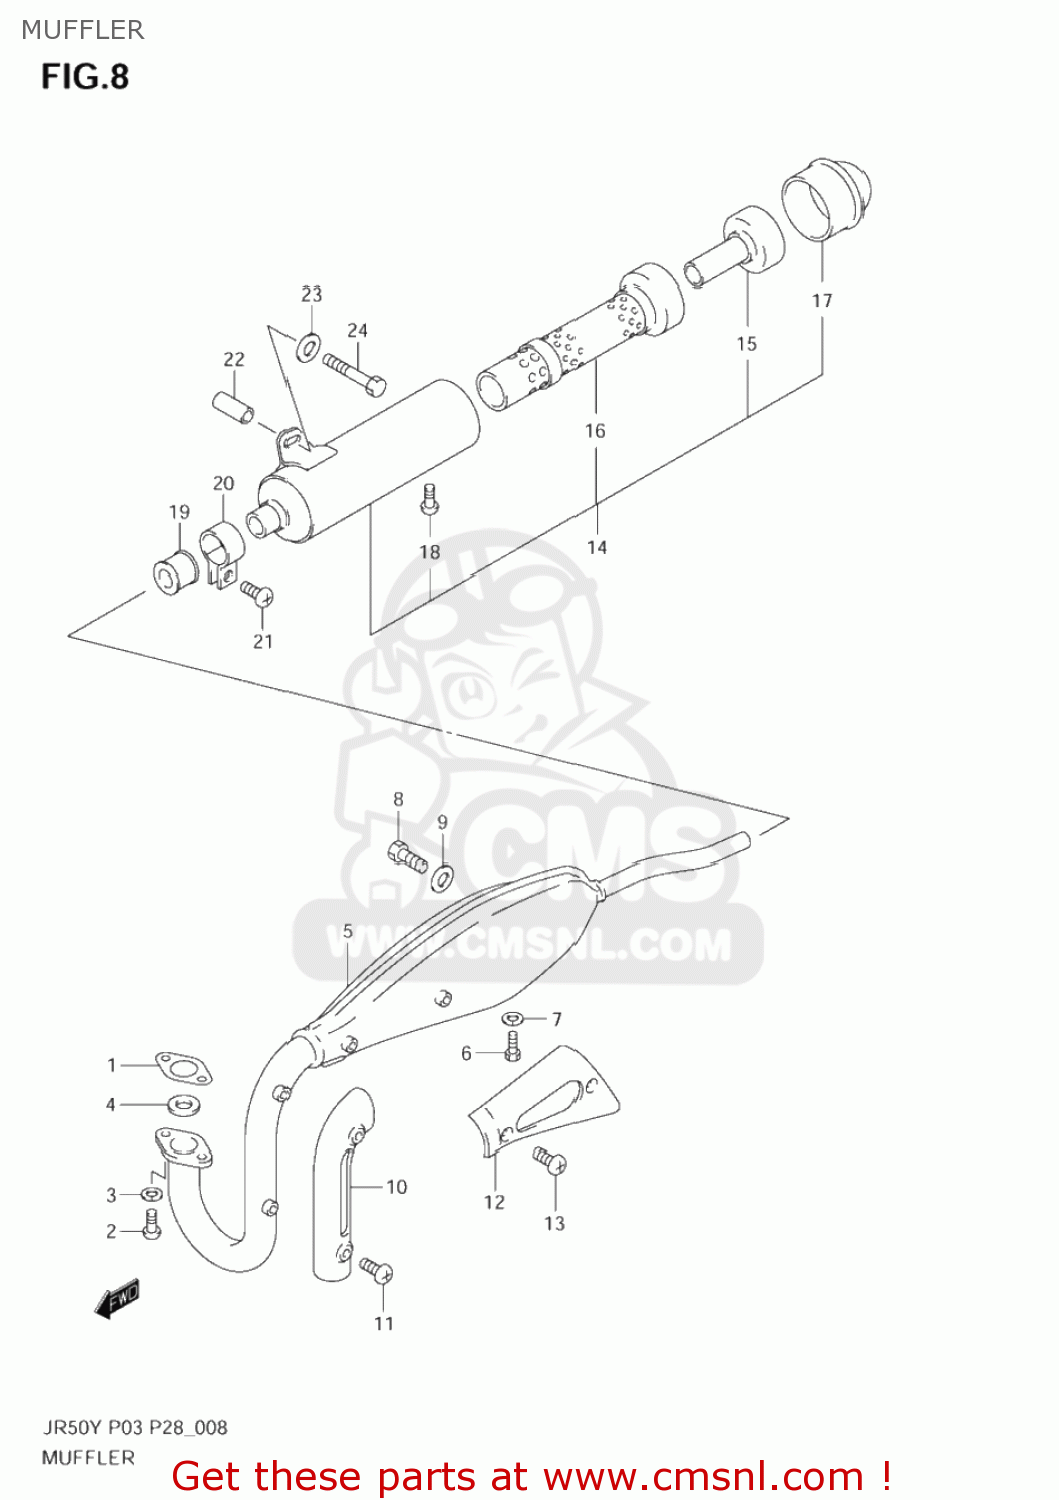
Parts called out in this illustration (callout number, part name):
1	GASKET,EXHAUST PIPE (NAS)
2	BOLT,OIL FILLE
3	LOCK WASHER
4	PLATE,EXHAUST PIPE
5	MUFFLER ASSY
6	BOLT
7	WASHER
8	BOLT, UPPER
9	WASHER (8.5X20X1.6)
10	COVER,EXHAUST PIPE
11	SCREW (M5X6)
12	COVER,MUFFLER
13	SCREW (M5X6)
14	MUFFLER ASSY,2ND
15	PIPE,BAFFLE
16	ARRESTER
17	CUTTER,MUFFLER TAIL
18	BOLT
19	CONNECTOR,MUFFLER
20	CLAMP
21	SCREW 6X16
22	SPACER,2ND MUF SPRT
23	WASHER
24	BOLT
